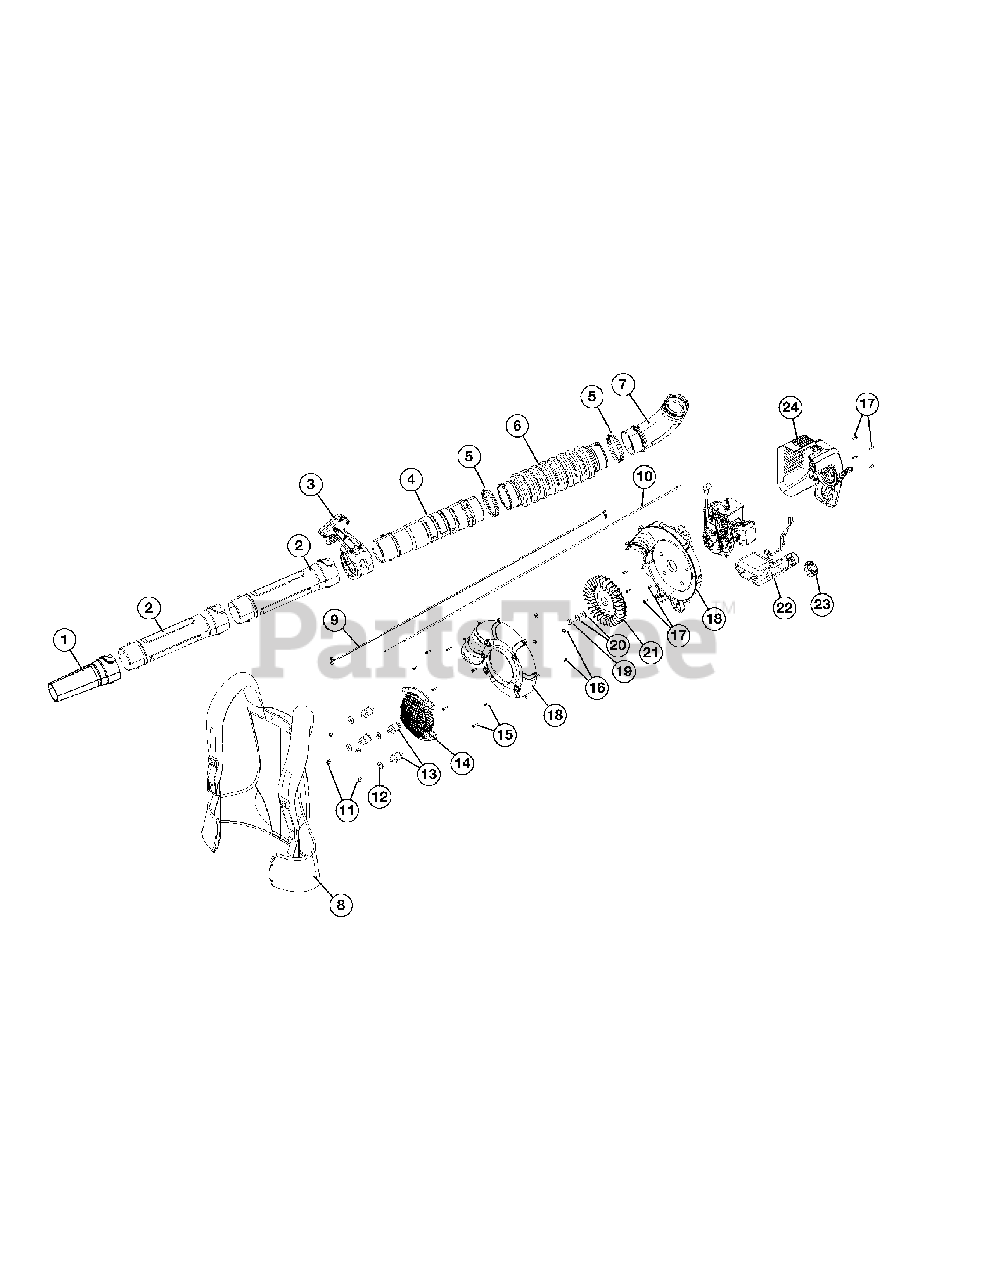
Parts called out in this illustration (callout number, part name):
2	Lower Blower Tube
3	Throttle Grip Assembly
4	Upper Blower Tube
8	Harness
10	Throttle Cable
11	Nut
13	Insulator Mount
14	Intake Cover
16	Nut
17	Screw
18	Impeller Housing Assembly
20	Impeller Hardware
22	Fuel Tank Assembly
24	Starter Housing Assembly
